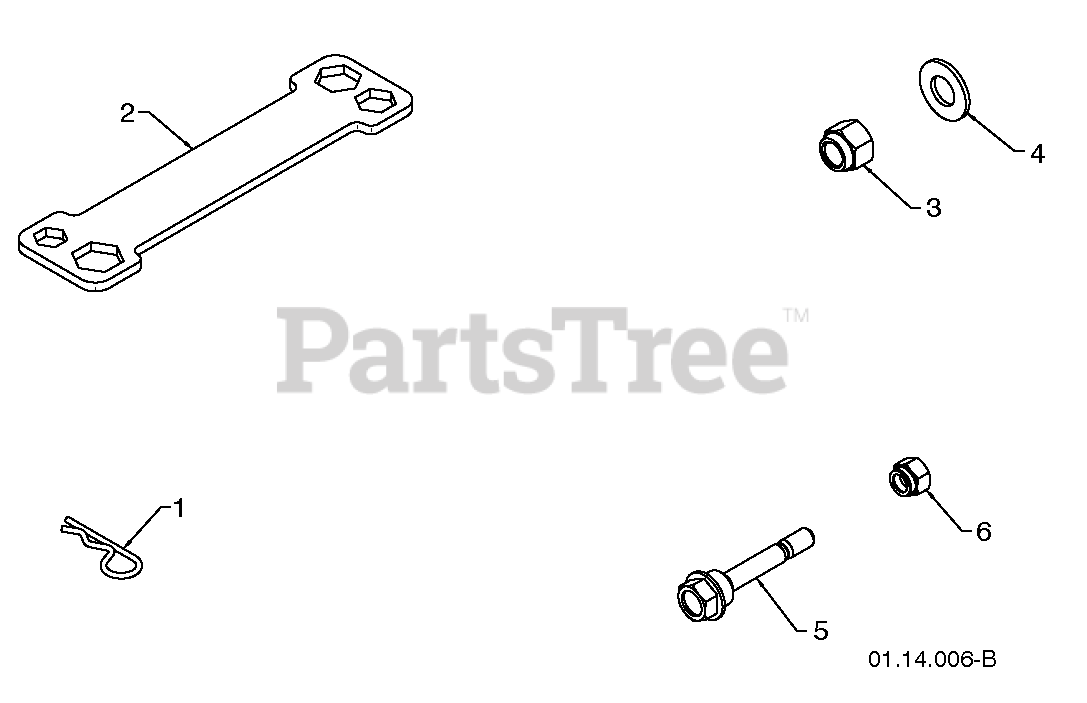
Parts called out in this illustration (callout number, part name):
1	RETAINER PIN
2	WRENCH
3	LOCKNUT 3/8-16
4	WASHER 3/8
5	SHEAR BOLT 1/4-20 X 1-13/16
6	LOCKNUT 1/4-20
